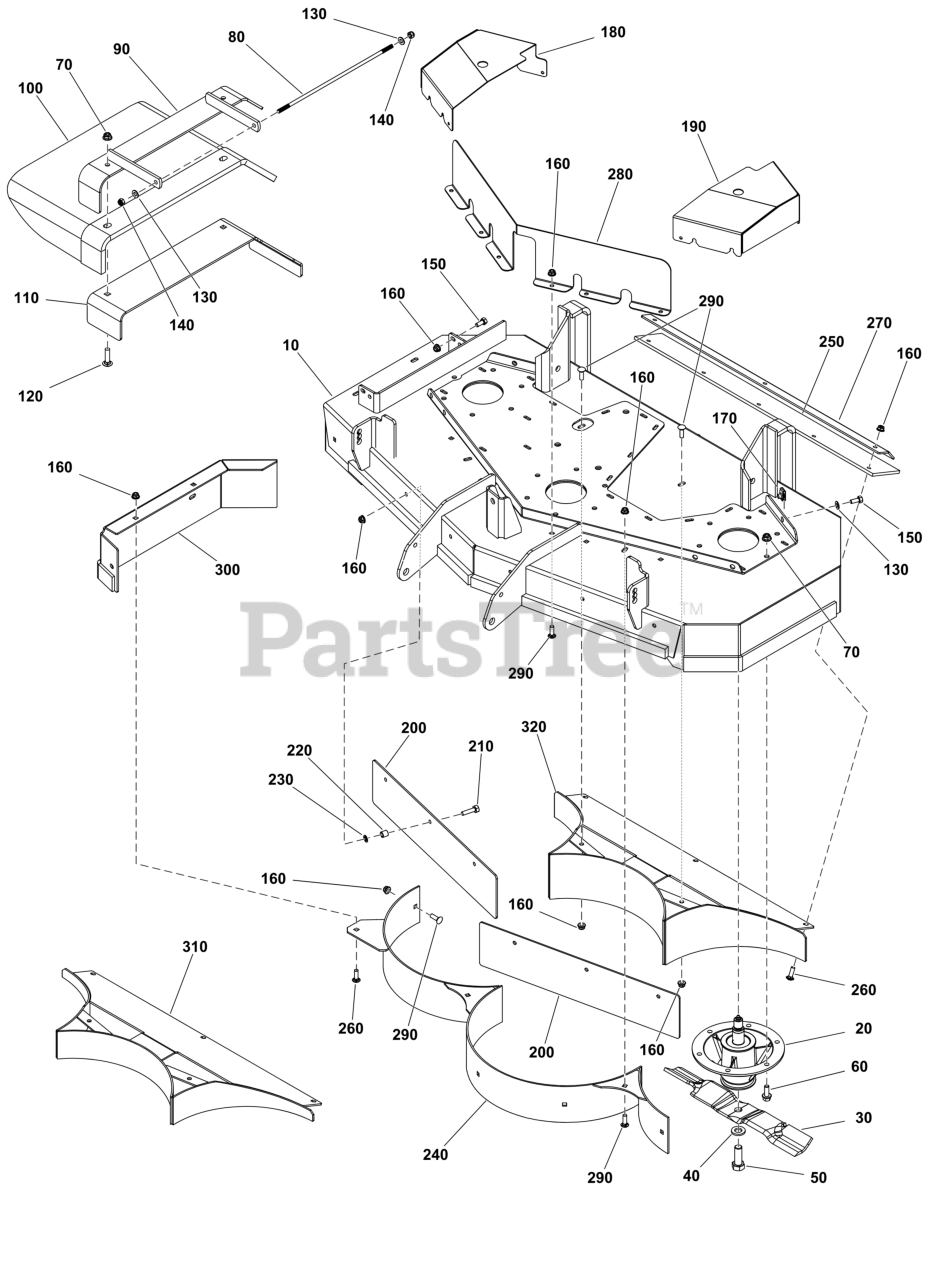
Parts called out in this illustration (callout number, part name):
10	DECK SHELL W/DECALS, FW45-SRDCE
20	SPINDLE ASSY
30	BLADE SET, MULCH, 48 DECK (SET OF 3)
40	WASHER, 5/8" YZ
50	BOLT
60	BOLT
70	NUT, 3/8-16 HEX NYLOCK
80	ROD, BRAKE LINKAGE
90	WELD, CHUTE MOUNT, 36/48, CE - BLK
100	CHUTE, RUBBER DISCHARGE CHUTE (5104441)
110	SUPPORT, DISCHARGE CHUTE, 48, CE - BLK
120	BOLT, 3/8-16 X 1-1/2
130	WASHER
140	NUT, 5/16-24 HEX NYLO
150	BOLT, 5/16-18 X 3/4"
160	NUT
170	BODY CLIP, 5/16-18 X
190	GUARD, PULLEY
200	BAFFLE, DISCHARGE
210	BOLT, 5/16-18 X 1-1/4
220	SPACER, .33 X .50X.50
230	NUT, PUSH ON, 5/16
240	BAFFLE, FRONT
260	BOLT, 5/16-18 X 1", C
270	BRACKET, Support
280	PLATE, FRONT GUARD, FW35 48",SD CE - RED
290	BOLT, 5/16-18 X 3/4",
300	PLATE, Blockoff
310	BAFFLE, Rear
320	BAFFLE, Rear
